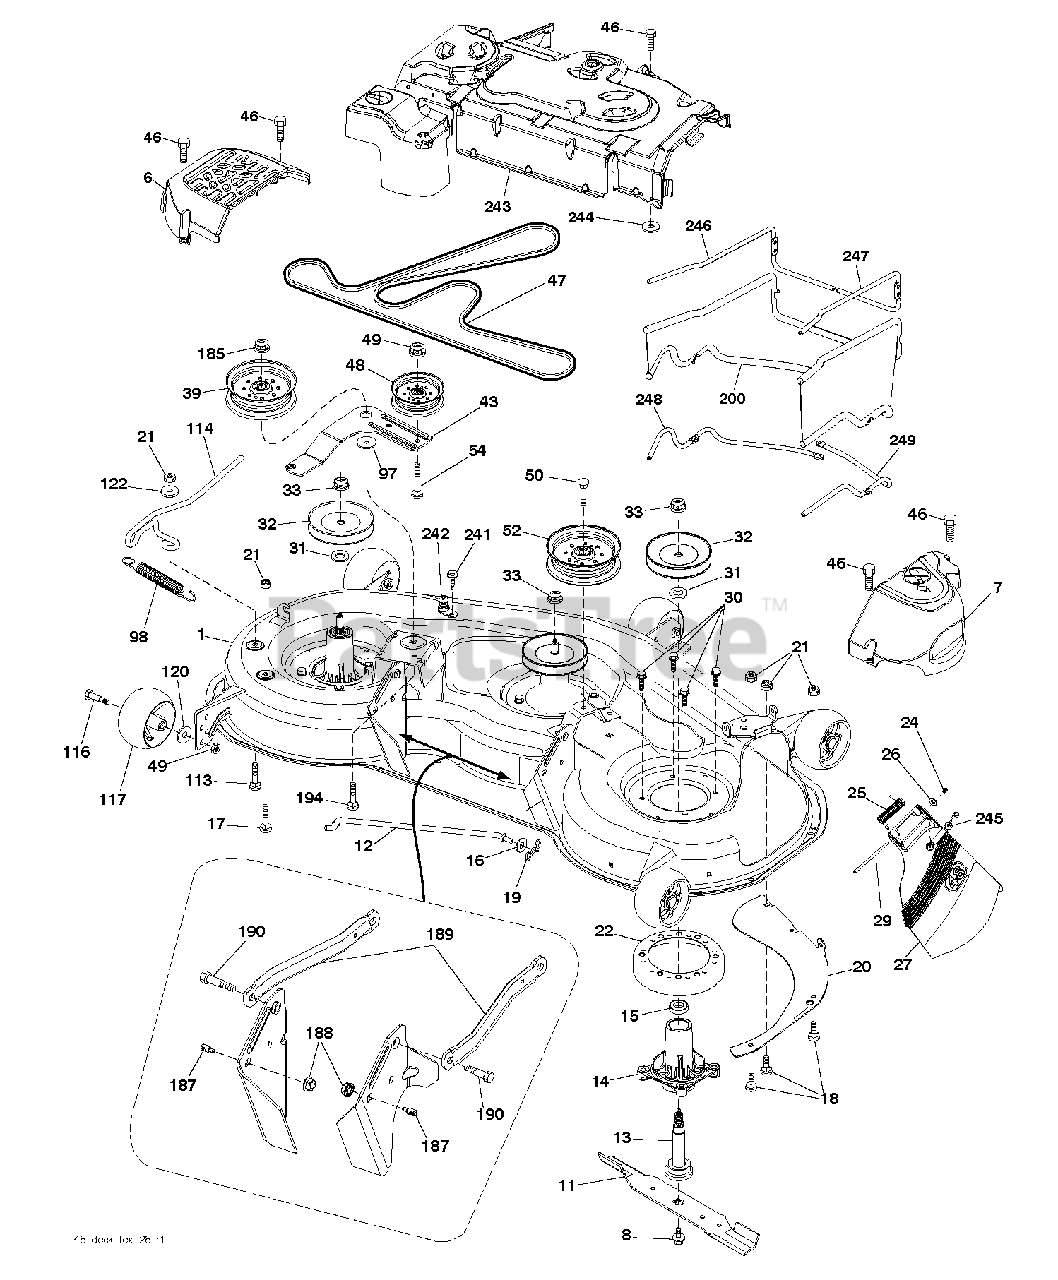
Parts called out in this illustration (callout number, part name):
6	COVER.MANDREL.LH.54"20
7	COVER.MANDREL.RH.54.20
8	BOLT.WASHER.ASM.7/16-2
12	ROD.ANTI.SWAY.48/54"TE
13	SHAFT ASM MANDREL
14	HOUSING.MANDREL.4PT.
16	WASHER
17	BOLT
18	BOLT
19	PIN.COTTER.5/16.BOW TI
20	BAFFLE, VORTEX MWR
21	LOCKNUT
22	STRIPPER.MANDREL.ROUND.BLACK
24	CAP-SLEEVE LT
25	SPRING, TORSION
26	NUT PUSH M
29	ROD.HINGE
30	SCREW, WASHER HEAD
31	WASHER.SPACER.MANDREL
32	PULLEY/MANDREL
33	NUT.FLANGE.LOCK.TOP
39	RB PULLEY.IDLER.4.50/HUB SPEC
46	SCREW.1/4-20X5/8
47	BELT.DRIVE.54."2006
48	PULLEY.IDLER.48"PRIMARY
49	NUT LOCK FLG 3/8-16 UNC
52	PULLEY.IDLER.2006
54	BOLT.3/8-16X1.50
98	SPRING, DECK DRIVE
114	ROD TENSION RELIEF
116	BOLT.SHOULDER.3/8-16X3-5/8.
117	WHEEL. GUAGE RALLY
120	WASHER
122	BUSHING.RELIEF.TENSION
185	NUT.LOCK.FLANGE.7/16
187	STUD.FASTNER.W/ANTI-ROTATE
188	NUT LOCK HEX FLANGE 5/16-18
189	ARM.SUSPENSION.MOWER
190	BOLT.SHOULDER
194	BOLT.HEX.WASHER.HEAD.7/16-24X
241	SCREW.TT.#10-32X.5.3/8.FLANGE
242	PORT.WASHOUT
244	PALNUT 1/4
245	ELASTIC STRAP KIT
